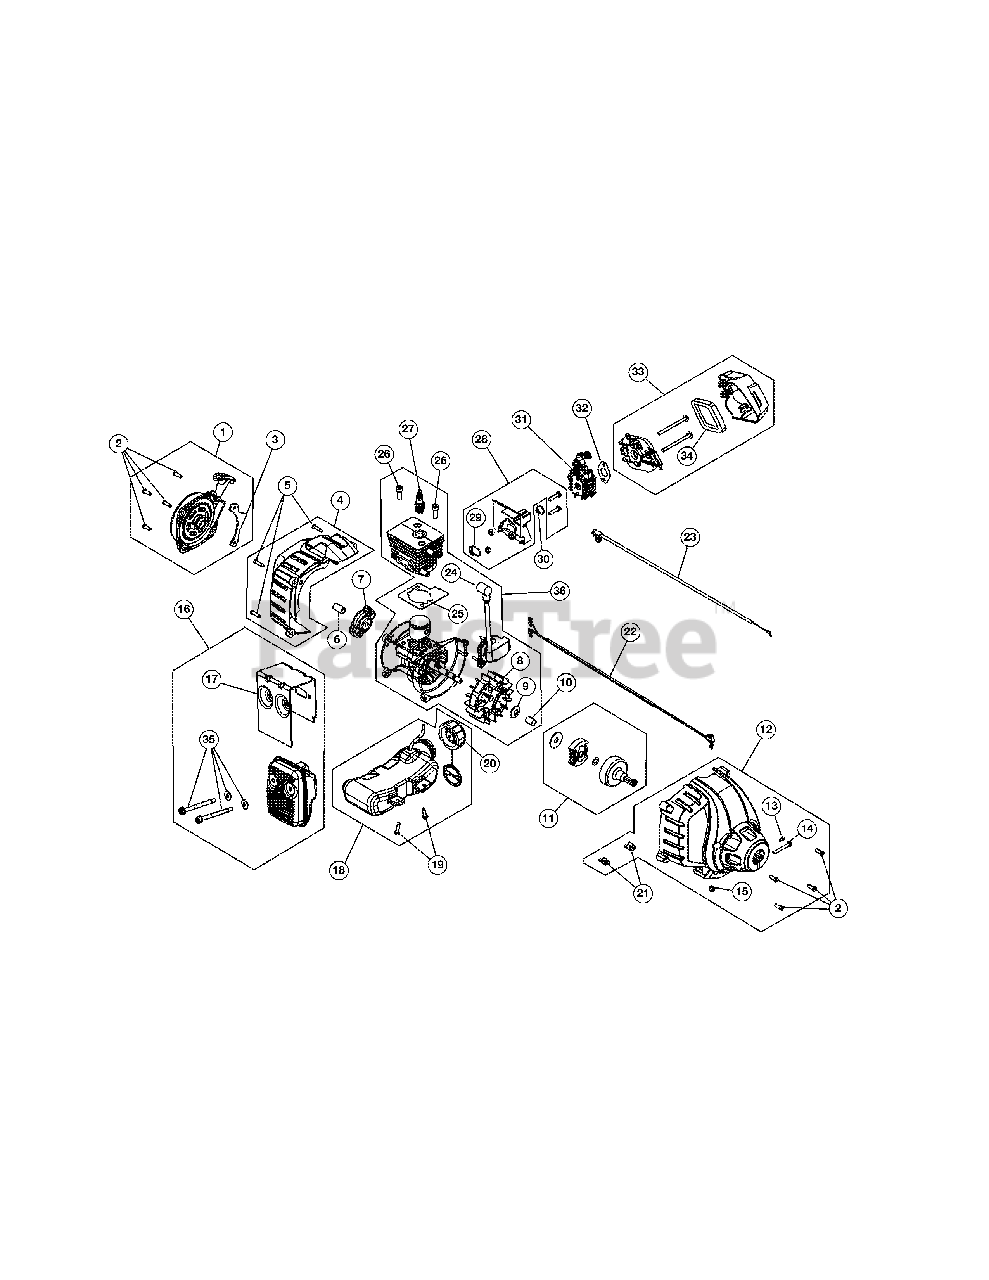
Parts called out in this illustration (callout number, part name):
1	Rear Cover Assembly (Incl. Ref No. 2 & 3)
2	Starter Screw
3	Starter Assembly Guard (Incl. Ref No. 2)
4	Rear Engine Cover (Incl. Ref No. 5)
5	Cover Screw
6	Adapter
7	Pawl Assembly
8	Flywheel Assembly
9	Washer
10	Spacer
11	Clutch Assembly
12	Clutch Cover Assembly (Incl. Ref No. 2, 13-15 & 21)
13	Anti-Rotation Screw
14	Clamp Screw
15	Clamp Nut
16	Muffler Assembly (Incl. Ref No. 17 & 35)
17	Muffler Gasket
18	Fuel Tank Assembly (Incl. Ref No. 19 & 20)
19	Tank Screw
20	Fuel Cap
21	U-Shaped Nut
22	Lead Wires
23	Throttle Cable
24	Module Assembly
25	Cylinder Gasket
26	Cylinder Bolt
27	Spark Plug
28	Insulator Assembly (Incl. Ref No. 29)
29	Insulator O-Ring
30	Carburetor O-Ring
31	Carburetor
32	Carburetor Gasket
33	Aircleaner Assembly (Incl. Ref No. 34)
34	Aircleaner Filter
35	Muffler Screw
36	Short Block Assembly
